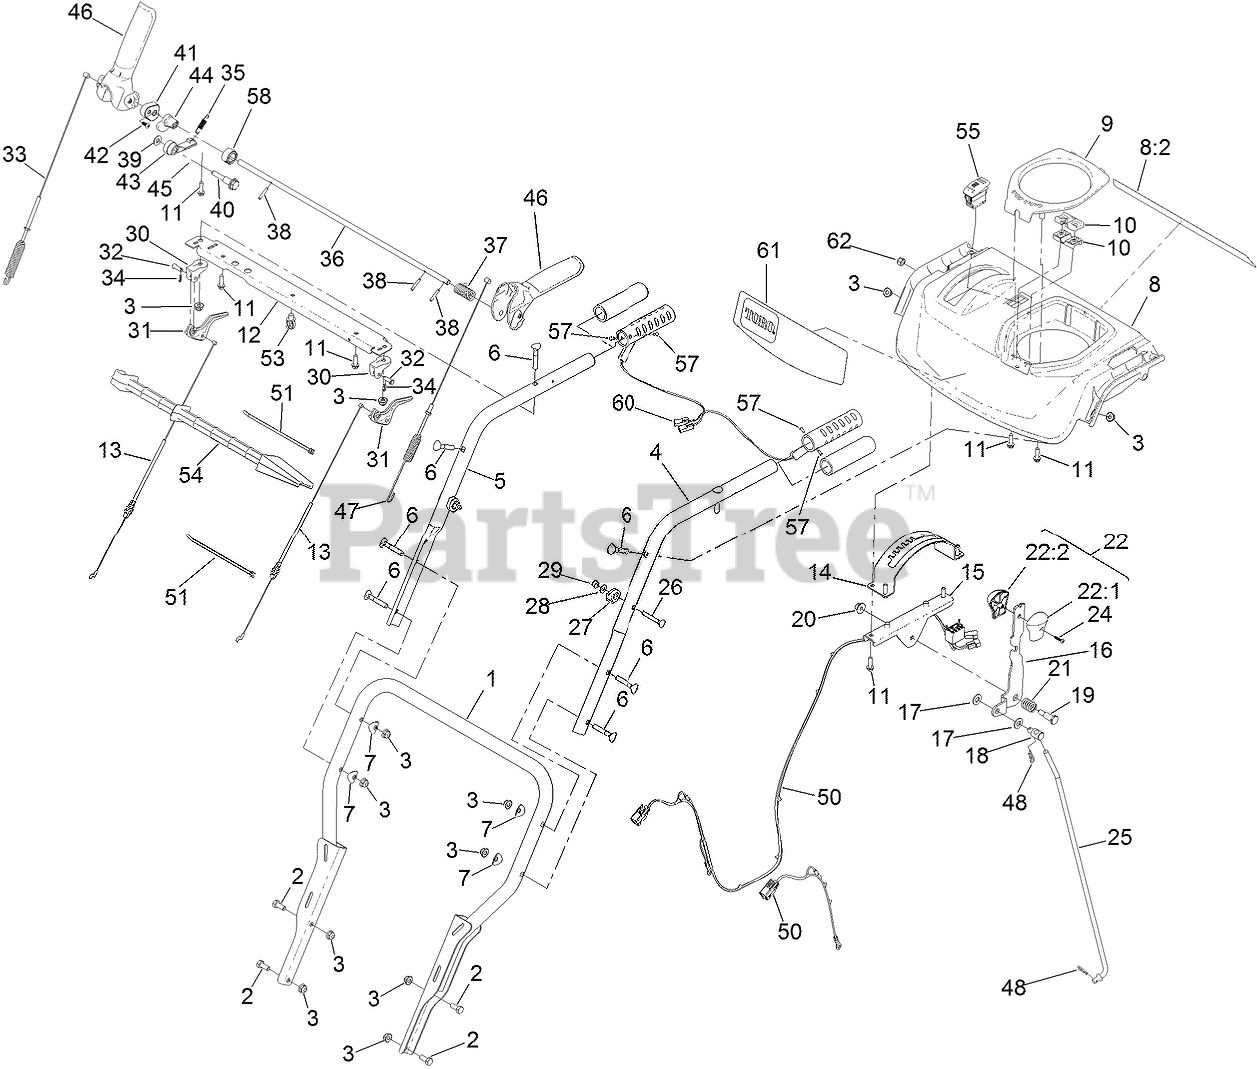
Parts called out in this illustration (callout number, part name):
1	LOWER HANDLE ASM
2	SCREW-HH
3	NUT-HF
4	HANDLE-UPPER, LH
5	HANDLE-UPPER, RH
6	SCREW-HANDLE
7	WASHER-CUP
8	PANEL-CONTROL
8:2	DECAL-SAFETY
9	COVER-QUICKSTICK
10	SUPPORT-ROD
11	SCREW-PLASTITE, HWH
12	BRACE-CONSOLE
13	CABLE-CLUTCH
14	GATE-SHIFT
15	BRACKET-SHIFT
16	SELECTOR-SPEED
17	WASHER-FLAT
18	TRUNNION-ROD
19	SCREW-SHOULDER, HH
20	NUT-HF
21	SPRING-COMPRESSION
22	SHIFT KNOB ASM
22:1	KNOB-SHIFT, LH
22:2	KNOB-SHIFT, RH
24	SCREW-PPH
25	ROD-SHIFT
26	BOLT-CARR
27	CLAMP-CABLE
28	WASHER-PLAIN
29	NUT-HEX
30	MOUNT-LEVER, CLUTCH
31	LEVER-CLUTCH
32	PIN-CLEVIS
33	CABLE-AUGER
34	PIN-HAIR
35	SPRING-LOCKOUT, HANDLE
36	ROD-LOCKOUT
37	SPRING-TORSION, HANDLE RETURN
38	PIN-SPRING
39	WASHER-FLAT
40	SCREW-SHOULDER
41	LOCK-HANDLE
42	SCREW-PPH
43	LATCH-LOCKOUT
44	CAM-LOCKOUT
45	LINK-LOCKOUT
46	LEVER-CONTROL
47	CABLE-TRACTION
48	PIN-HAIR
50	HARNESS-WIRE, LED AND HAND WARMERS
51	TIE-CABLE
53	CLIP-TIE
54	STICK-CLEANOUT
55	SWITCH-ROCKER, ON-NONE-OFF (HEATER)
57	RIVET-POP
58	COLLAR-CAM
60	GRIP-HEATED
61	DECAL-CONSOLE
62	NUT-HEX
